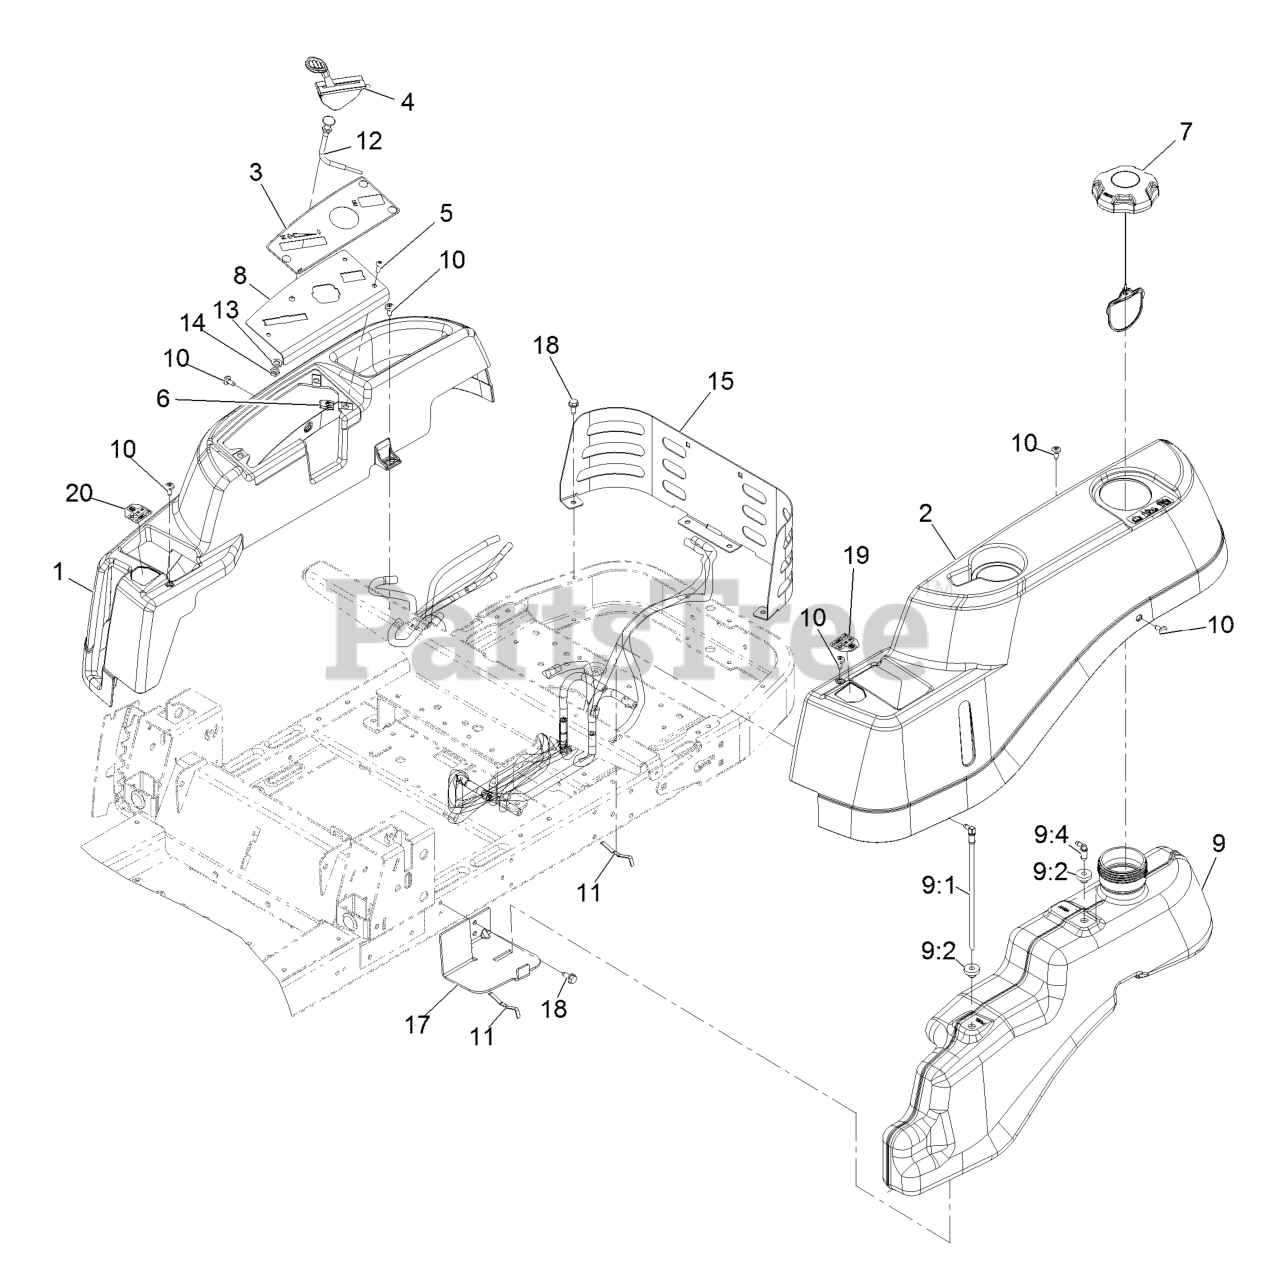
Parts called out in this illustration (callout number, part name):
3	DECAL-CONTROL PANEL
4	CABLE-THROTTLE
5	SCREW-PRH
6	Nut-Retainer-Panel 1/4-20
8	PLATE-CONTROL
9	FUEL TANK ASM
9:1	CONNECTOR-ELBOW, 90 DEG
9:2	BUSHING
9:4	FITTING-PLASTIC
10	SCREW-SHOULDER
11	SPRING
12	CABLE-CHOKE
13	WASHER-LOCK
14	NUT-HJ
15	GUARD-REAR, NARROW
17	SUPPORT-TANK, FRONT
18	Screw-HWH 5/16-18 X 3/4 Tf
19	DECAL-LEVER, CONTROL (LH)
20	DECAL-LEVER, CONTROL (RH)
